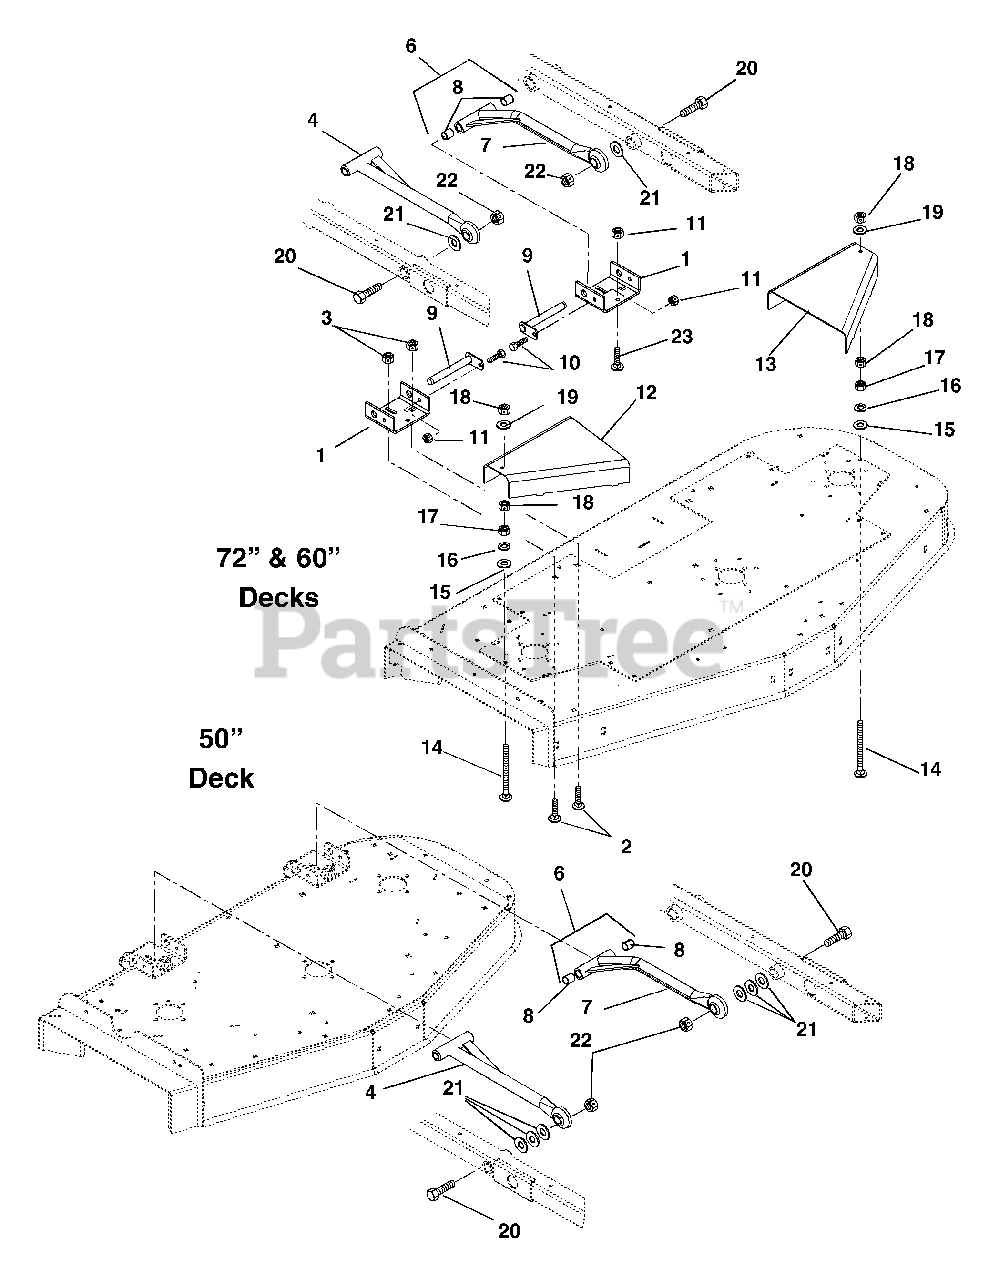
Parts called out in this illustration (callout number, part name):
1	Bracket, Mower Mounting (Rear) (60" & 72" Deck)
2	Bolt-Round Head Square Neck .50-13 x 1.00 Grade 2
3	Nut-Locking-Center .50-13
4	Assembly, Mower Mounting Arm
5	Weldment-Mower Mounting Arm
6	Assembly, Mower Mounting Arm Left Hand
7	Weldment, Mower Mount Arm
8	Bearing .75 x .875 x 1.00
9	Weldment, Mower Mounting Pin
10	Bolt-Hex .38-16 x .75 Grade 5
11	Nut-Locking-Center .38-16
12	Guard, Pulley Right Hand (60" Deck)
12	Guard, Pulley Right Hand (50" Deck)
12	Guard, Pulley Right Hand (72" Deck)
13	Guard, Pulley Left Hand (60" Deck)
13	Guard, Pulley Left Hand (50" Deck)
13	Guard, Pulley Left Hand (72" Deck)
14	Bolt-Round Head Square Neck .31-18 x 3.50
15	Washer-Flat-Steel .344 x .688 x .065
16	Washer-Locking .31 x .078
17	Nut-Hex .31-18
18	Nut-Locking-Center .31-18
19	Washer-Flat-Steel .438 x 1.00 x.083
20	Bolt-Hex .875-9 x 2.75 Grade 5
21	Washer-Flat-Steel .875 x 1.500 x .1196 (60" & 72" Deck)
21	Washer-Flat-Steel .875 x 1.500 x .1196 (50" Deck)
22	Nut-Locking-Center .875-9
23	Bolt-Round Head Square Neck .38-16 x 1.00 Grade 5 (60" & 72" Deck)
23	Bolt-Round Head Square Neck .38-16 x 1.00 Grade 5 (50" Deck)
